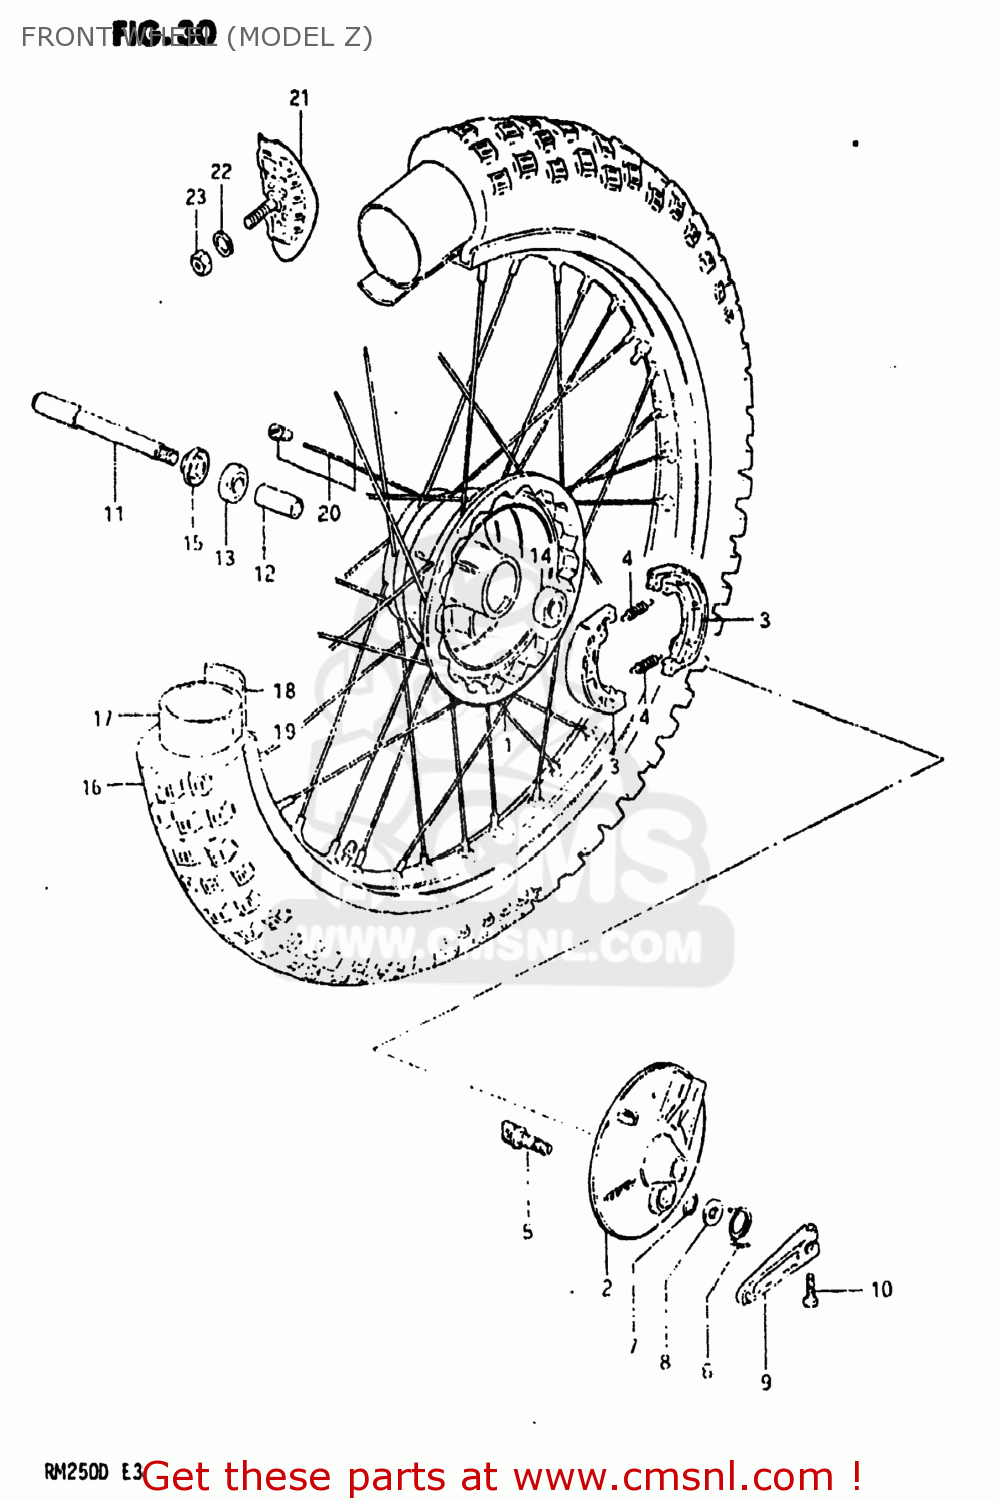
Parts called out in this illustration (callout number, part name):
1	HUB,FRONT
2	PANEL,FRONT HUB
3	SHOE,BRAKE
4	SPRING
5	CAM,FRONT BRAKE
6	SPRING
7	O RING(D:2.5,ID:11.4)
8	WASHER(12.5X20X1)
9	LEVER,FRONT BRAKE CAM
10	BOLT
11	AXLE,FRONT
12	SPACER,FRONT HUB BEARING
13	BEARING
14	BEARING
15	SPACER,FRONT AXLE,RIGHT
16	TIRE,FRONT
17	TUBE,INNER
18	PROTECTOR,WHEEL,INNER
19	RIM,FRONT WHEEL
20	SPOKE SET,FRONT
21	STOPPER,BEAD
22	WASHER
23	NUT 8MM
